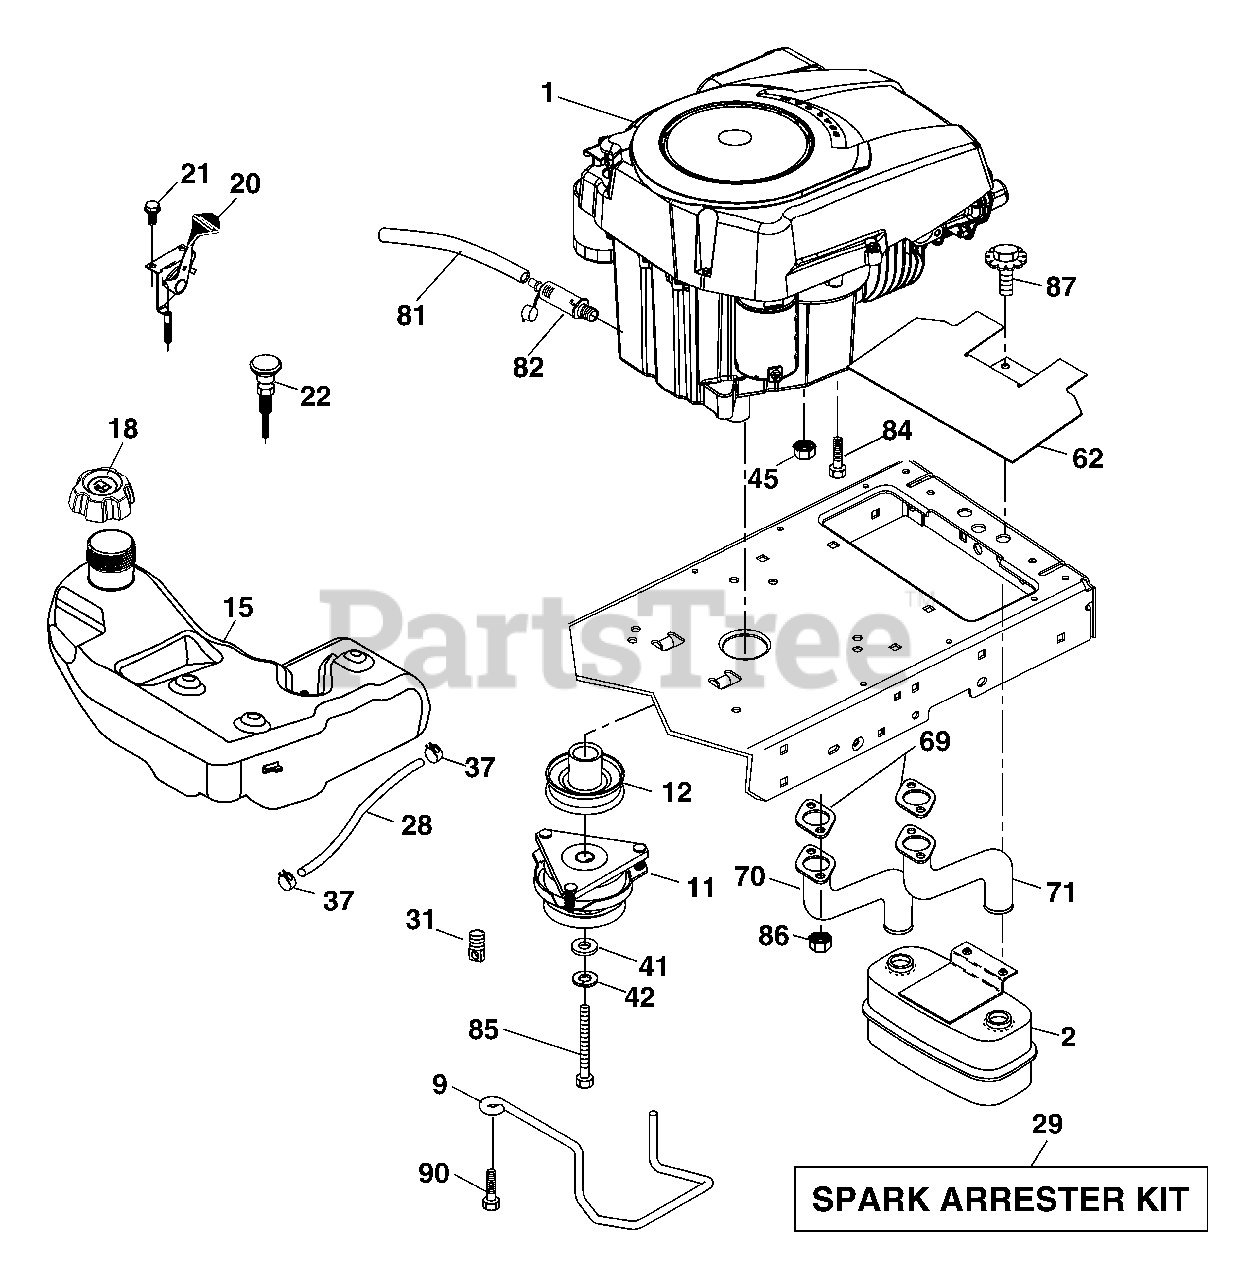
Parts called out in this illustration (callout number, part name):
9	Keeper Belt Engine
11	Clutch Electric
12	Pulley Engine
15	Tank Fuel 4.0
18	Cap Asm
20	Control Throttle
21	Screw 10 x 3/4 Single Lead Hex
22	Control Choke
28	Fuel Line
29	Spark Arrester Kit
31	Clip Push-In
37	Clamp Hose
41	Washer 1-1/2 OD x 15/32 ID x .250
42	Washer Lock 7/16
45	Nut Keps Hex 1/4-20 unc
62	Shield Heat Muffler
69	Gasket
70	Tube Exhaust LH
71	Tube Exhaust RH
81	Tube Drain Oil Easy
82	Plug Drain Oil
84	Screw 3/8-16 x 1 1/4
85	Bolt Hex 7/16-20 x 3.75 Gr. 5
86	Nut Hex Flange Toplock M8-1.25
87	Bolt 5/16-18 unc x 1 w/Sems
90	Screw 3/8-16 x 1
